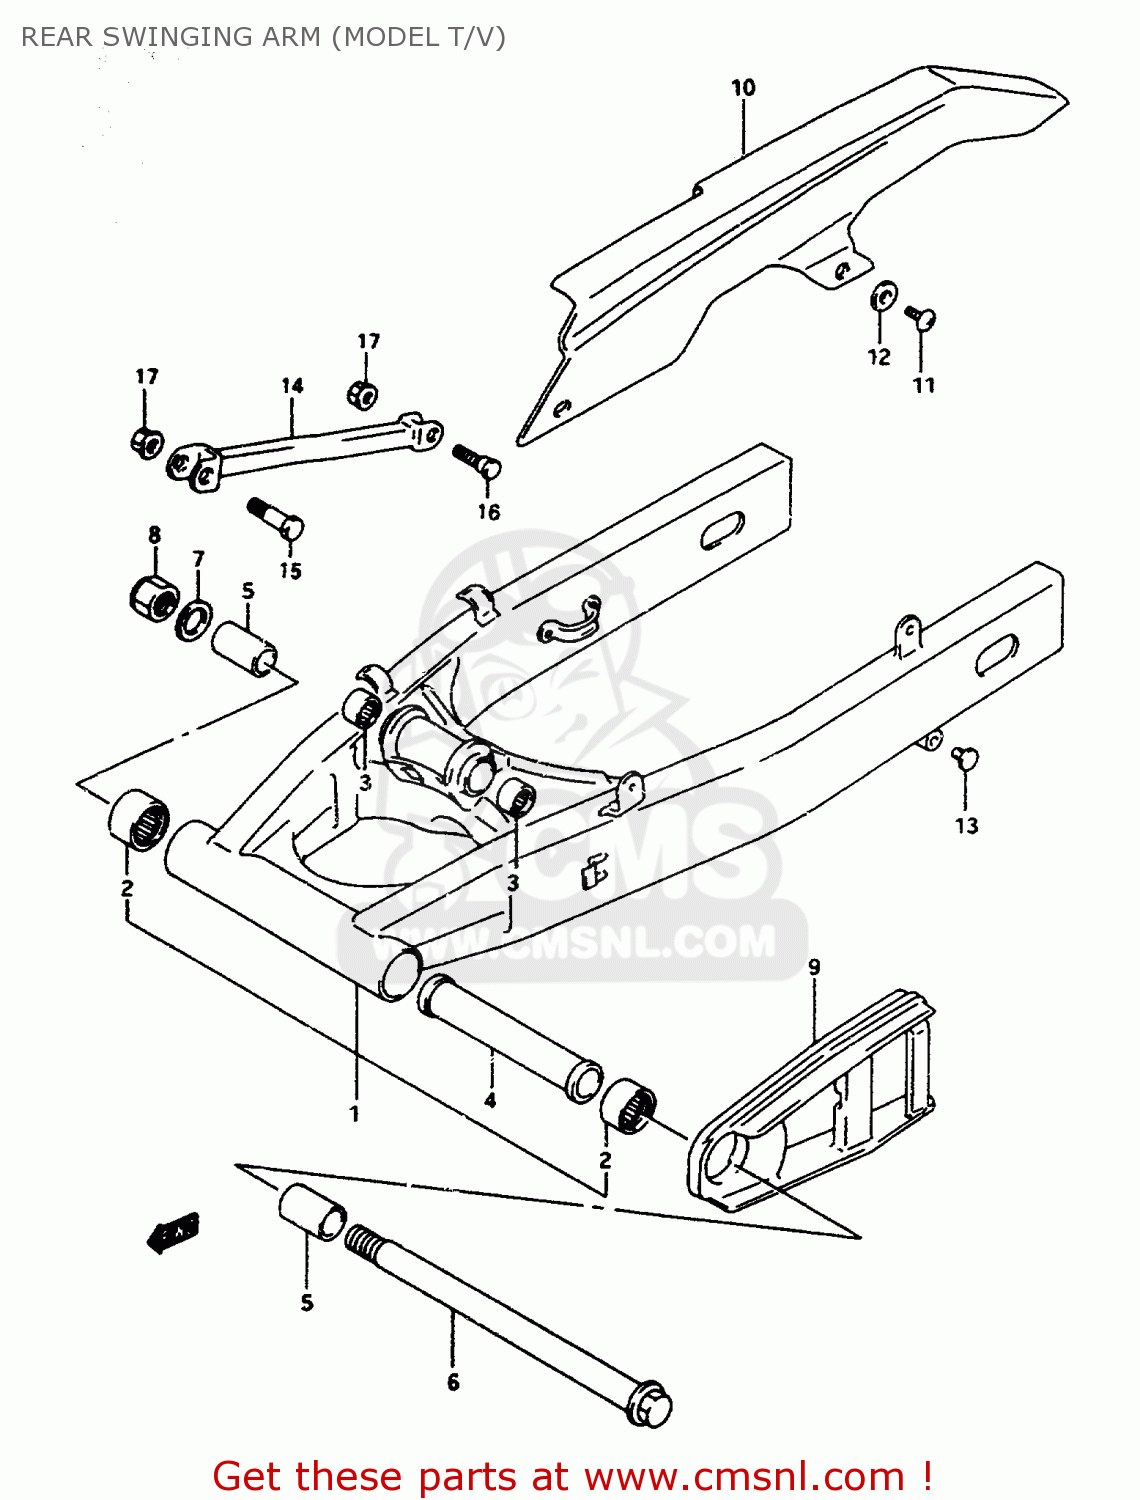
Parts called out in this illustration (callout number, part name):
1	SWING ARM ASSEMBLY,REAR (
2	BEARING(25X33X35)
3	BEARING(17X24X25)
4	SPACER(20.8X27.2X146)
5	SPACER,RR SWGARM PIVOT
6	SHAFT,REAR SWING ARM
7	WASHER (18.2X28X2.6)
8	NUT
9	BUFFER,CHAIN TOUCH DEFENSE
10	CASE,CHAIN
11	SCREW 6X12
12	WASHER
13	CAP(OD:12)
14	TORQUELINK,RR
15	BOLT(10X39)
16	BOLT(10X34)
17	NUT
